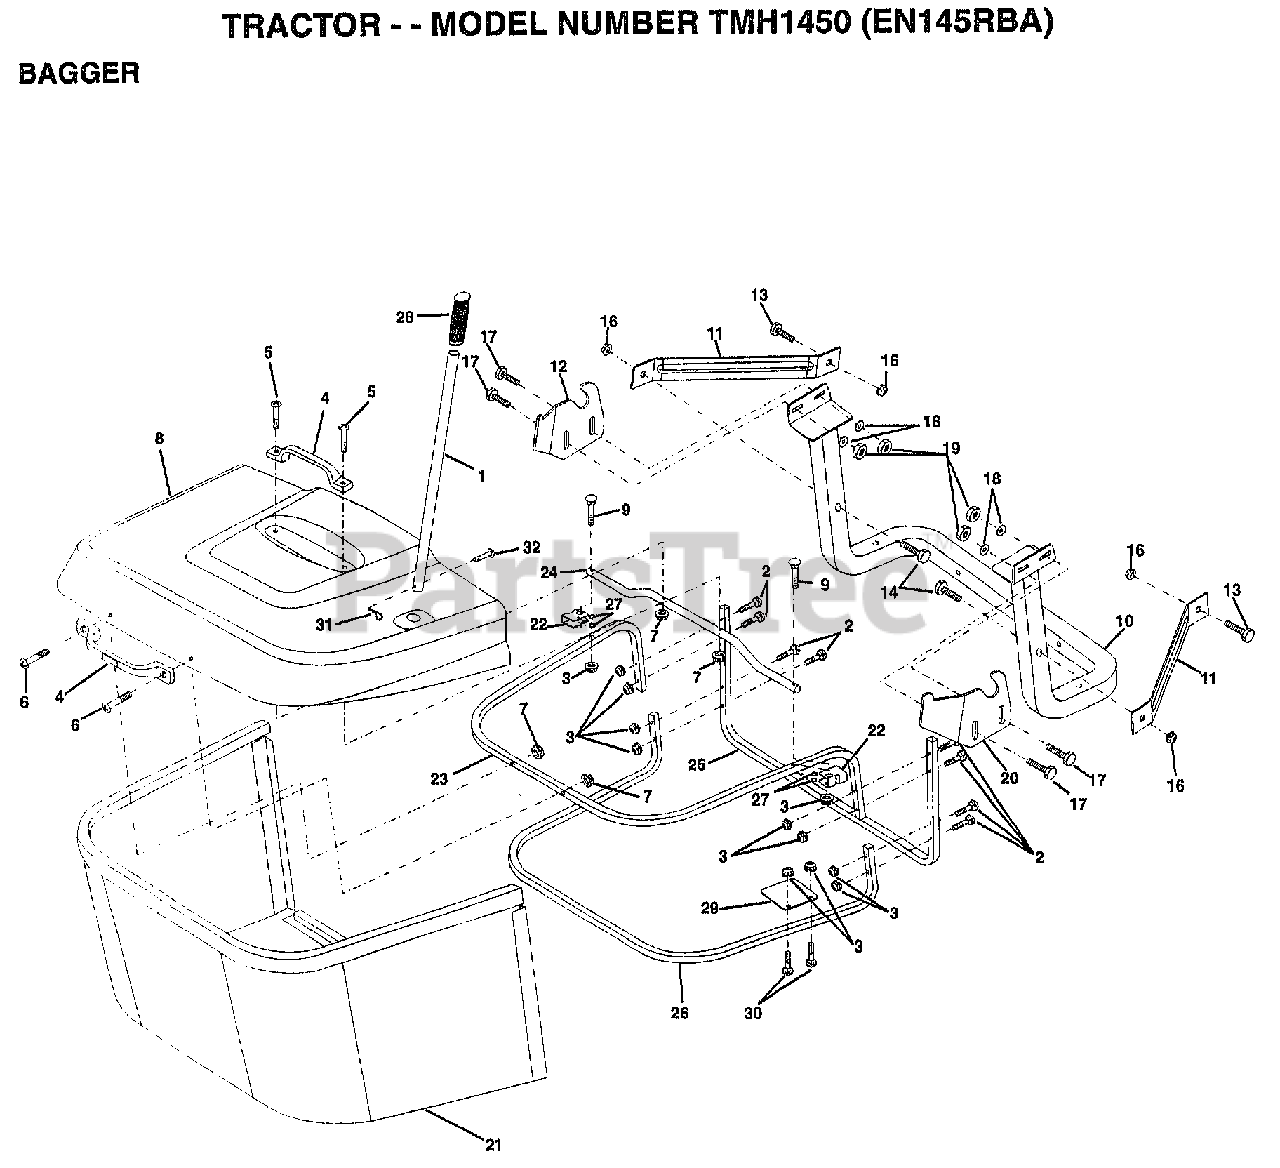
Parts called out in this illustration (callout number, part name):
1	TUBE.HDLE.BAG.CRD
2	BOLT.CARRIAGE.1/4-20X2.0
4	HANDLE.GRAB.BLACK.
5	"SCREW,PAN.HEAD"
7	NUT.WIZ.LOCK
8	COVER BAGGER PLASTIC
9	BOLT CARRIAGE
10	SUPT.ASM.WLDMNT.BAG.CRD
11	BRKT.SUPT.UPPER.BAG.CRD
12	BRKT.PIVOT.BAG.LH.CRD
13	BOLT
14	BOLT.HEX.3/8-16X2-1/2
17	BOLT
18	WASHER
19	NUT
20	"BRKT.PIVOT.BAG,RH.CRD"
21	BAG.ASM.CRD
22	BRKT.SIDE.BAG.CRD
23	TUBE.UPPER.BAG.CRD
24	TUBE.PIVOT.BAG.CRD
25	TUBE.FT.BAG.CRD
26	TUBE.LOWER.BAG.CRD.
27	GROMMET.EXTRUDED
28	GRIP.HANDLE.BLACK
29	PLATE.STOP.BAG.HDLE.CRD
30	BOLT.CARRIAGE
31	RETAINER M
32	RIVET.DRILL.1.75
